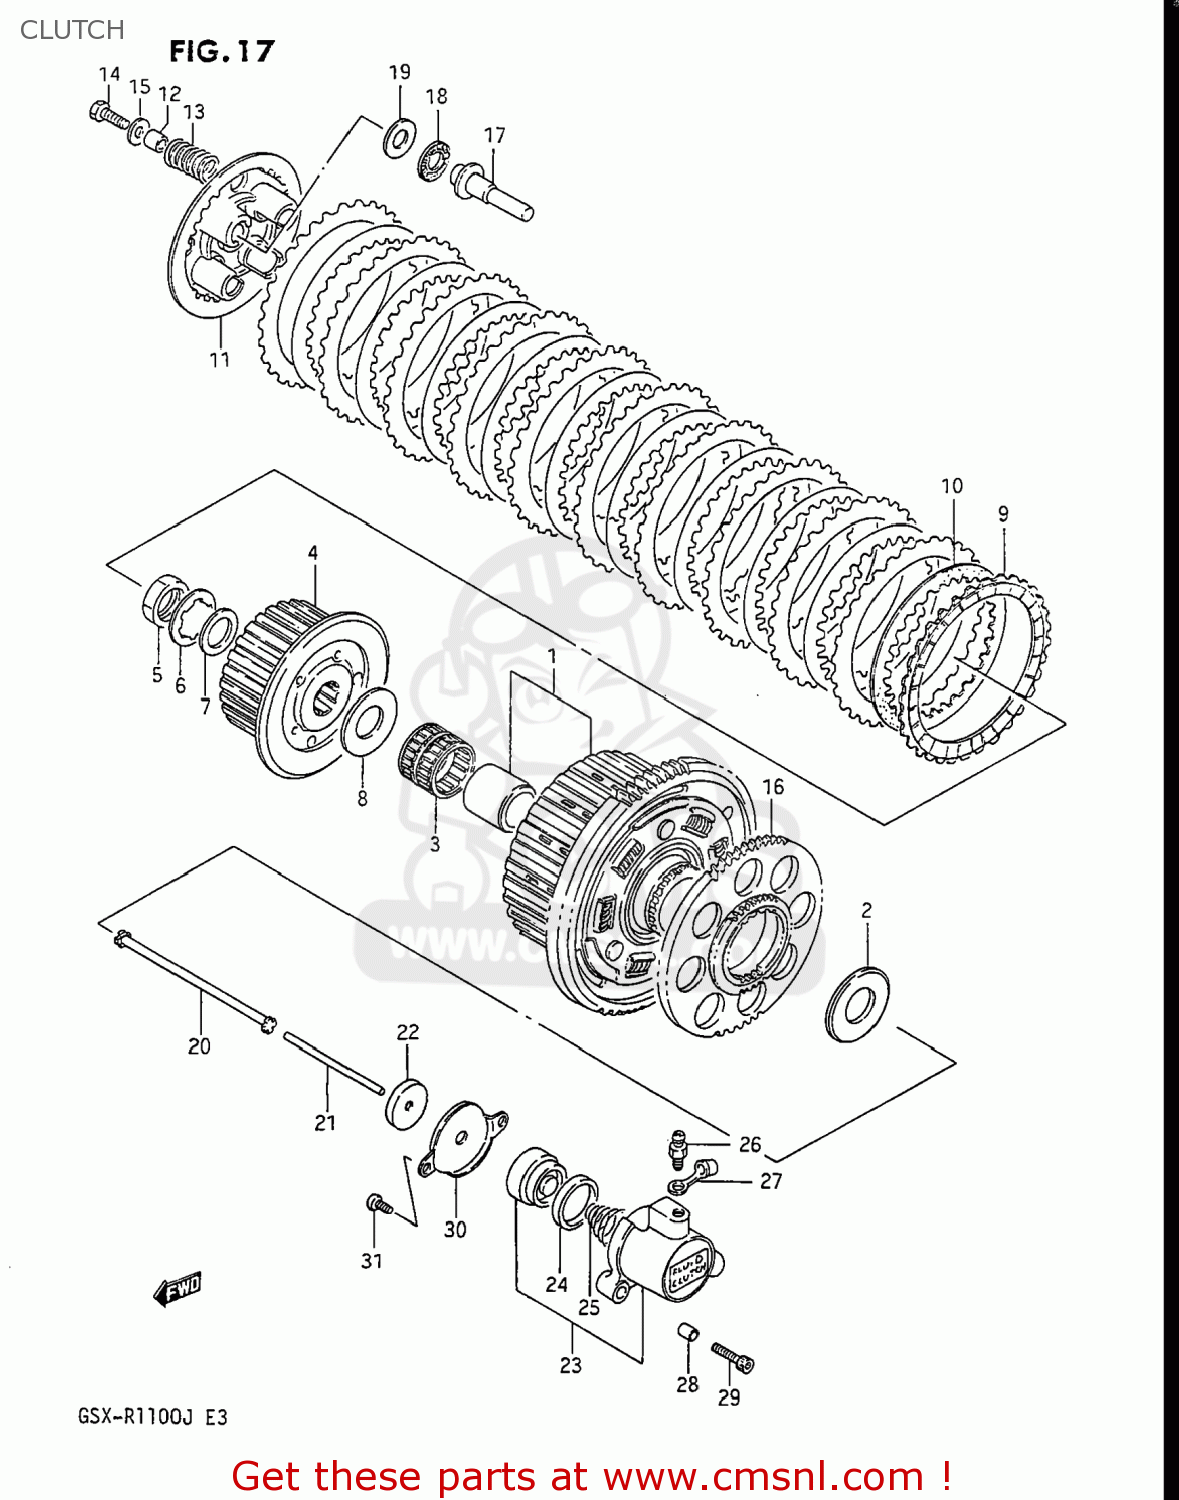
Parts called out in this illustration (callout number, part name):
1	GEAR ASSEMBLY,PRIMARY DRIVE
2	WASHER
3	BEARING(35X40X35.8)
4	HUB,CLUTCH SLEEVE
5	NUT
6	WASHER,LOCK
7	WASHER
8	WASHER(25X50X2.5)
9	PLATE,CLUTCH DRIVE (MCA)
10	PLATE,CLUTCH DRIVEN (NAS)
11	DISC,CLUTCH PRESSURE
12	SPACER(6.2X12X14)
13	SPRING
14	BOLT 6X30
15	WASHER
16	GEAR,GENERATOR DRIVE
17	PIECE,CLUTCH PUSH
18	BEARING(15X28X2)
19	WASHER
20	ROD,CLUTCH
21	ROD,CLUTCH PUSH,L
22	SEAL,OIL(6X34X5.5)
23	CYLINDER,CLUTCH RELEASE
24	CUP
25	SPRING,CLUTCH CYLINDER
26	BLEEDER
27	CAP,BLEEDER
28	PIN
29	BOLT
30	PLATE,CLUTCH PUSH ROD
31	SCREW
